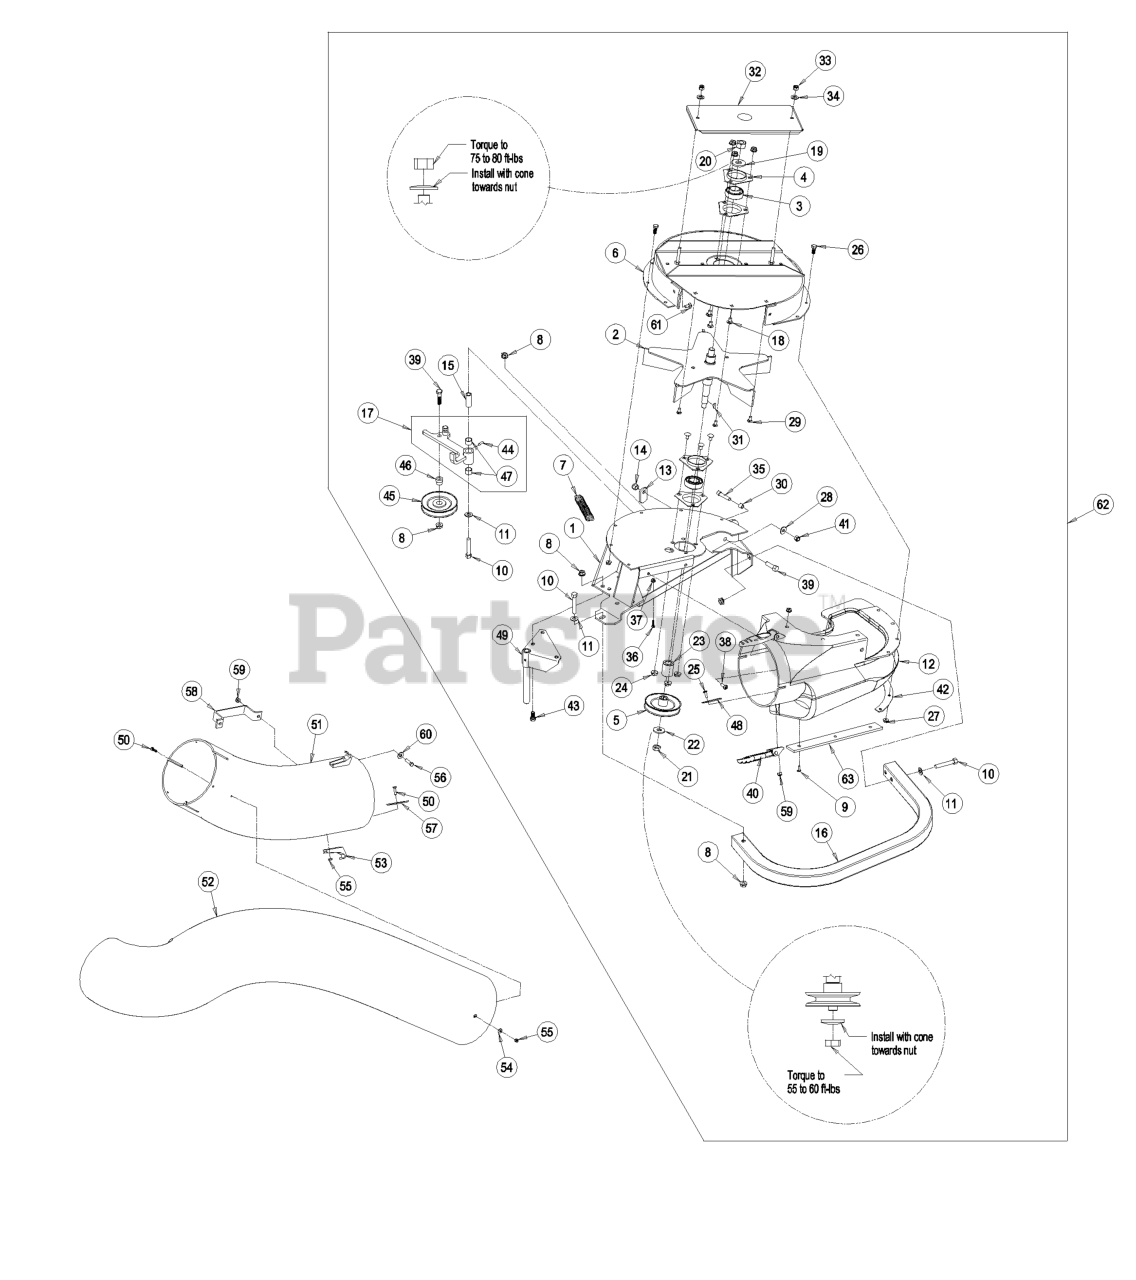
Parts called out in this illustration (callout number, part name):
1	WLD,BLOWER MOUNT
2	IMPELLER
3	BEARING
4	HOUSING-FLANGE
5	SHEAVE
6	ASM, UPPER HSG
7	SPRING-IDLER
8	NUT-HHF, WHIZ
9	RIVET-BLIND
10	SCREW-HH
11	WASHER-FLAT
12	ASM,BLOWER CHUTE LZ
13	LATCH-CATCHER, GRASS
14	NUT-LOCK, NI
15	BUSHING
17	ASM, IDLER ARM - SERVICE
18	SCREW-CARR
19	WASHER-SPRING
20	NUT-HEX
21	NUT-JAM
22	WASHER-SPRING
25	SCREW-HH
26	SCREW-HH
28	WASHER-SPRING
29	SCREW-CARR
30	BUSHING, LOCATOR
31	KEY-WOODRUFF
32	ASM, BEARING COVER
33	NUT-LOCK, NI
34	WASHER-FLAT
35	SCREW-HSH
36	SCREW-HEAD, TRUSS
39	SCREW-HH
40	LATCH-RUBBER
41	NUT-HEX
42	PLATE-BACKING, BLOWER
43	SCREW-HH
44	FITTING-GREASE
46	HUB,SPACER
47	BUSHING
48	PLATE-BACKING
49	PIN-MOUNT
50	SCREW-HWH
51	TUBE-LOWER
53	LATCH-CATCH
54	WASHER-FLAT
55	NUT-LOCK, NI
56	SCREW-HH
57	PLATE-BACKING
59	NUT-LOCK, NI
60	WASHER-FLAT
61	BOLT-CARR
62	Asm, Blower
63	PLATE,REINFORCEMENT LARGE
